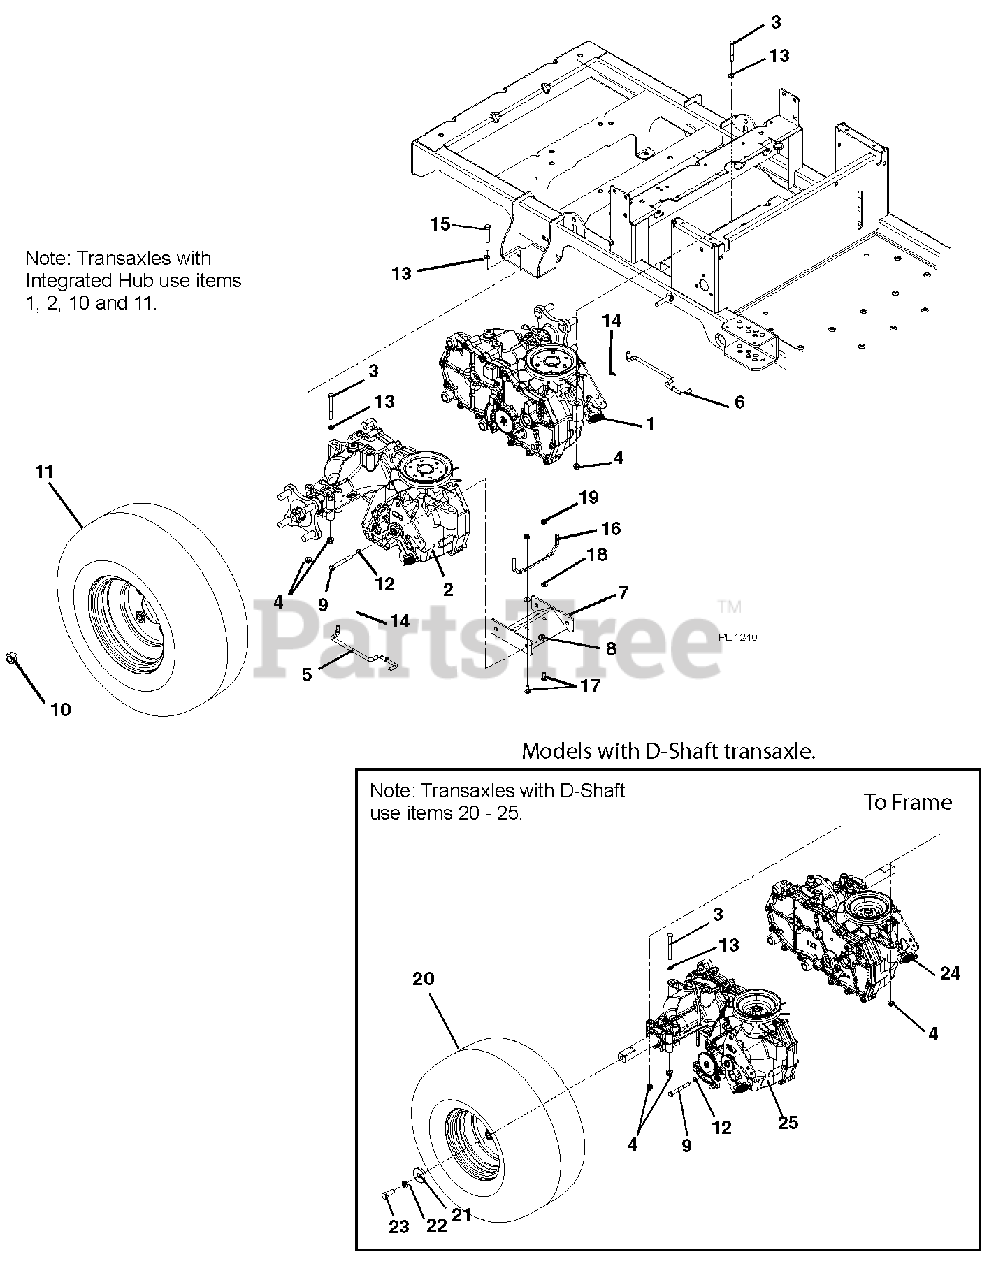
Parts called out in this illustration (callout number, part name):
1	Transaxle, EZT Short Left Hand
2	Transaxle, EZT Short Right Hand
3	Bolt, Hex .31-18 x 2.25 Grade 5
4	Nut 5/16-18 Flange Nyloc
5	Dump Valve, Right Hand
6	Dump Valve, Left Hand
7	Weldment, Transaxle Brace
8	Nut, Nyloc Flange .38-16
9	Bolt-Hex .38-16 x 2.50 Grade 5
10	Nut, Wheel .50-20 13/16
11	Tire/Wheel Assembly, 18 x 6.5-8 Offset
12	Washer, Flat Steel .406 x 1.00 x .188
13	Washer-Flat-Steel .38 x .875 x .083
14	Pin-Hair-Internal .06 x .18 x .77
15	Bolt, Hex .31-18 x 2.75
16	Belt Finger, Drive Sheave
17	Bolt, Round Head Square Neck .25-20 x .75 Grade 5
18	Washer, Flat-Steel .281 x .62 x .065
19	Nut, Locking Nylon Flange 1/4-20
20	Tire, Assembly 18 x 6.5-8 2 Pulley D-Shaft (with D-Shaft Transaxle)
21	Washer, Flat Steel .406 x 1.50 x .245 (with D-Shaft Transaxle)
22	Washer, Locking .38 x .094 Regular (with D-Shaft Transaxle)
23	Bolt, Hex .38-16 x 1.00 Grade 5 (with D-Shaft Transaxle)
24	Transaxle, Left Hand EZT D-Shaft (with D-Shaft Transaxle)
25	Transaxle, Right Hand EZT D-Shaft (with D-Shaft Transaxle)
